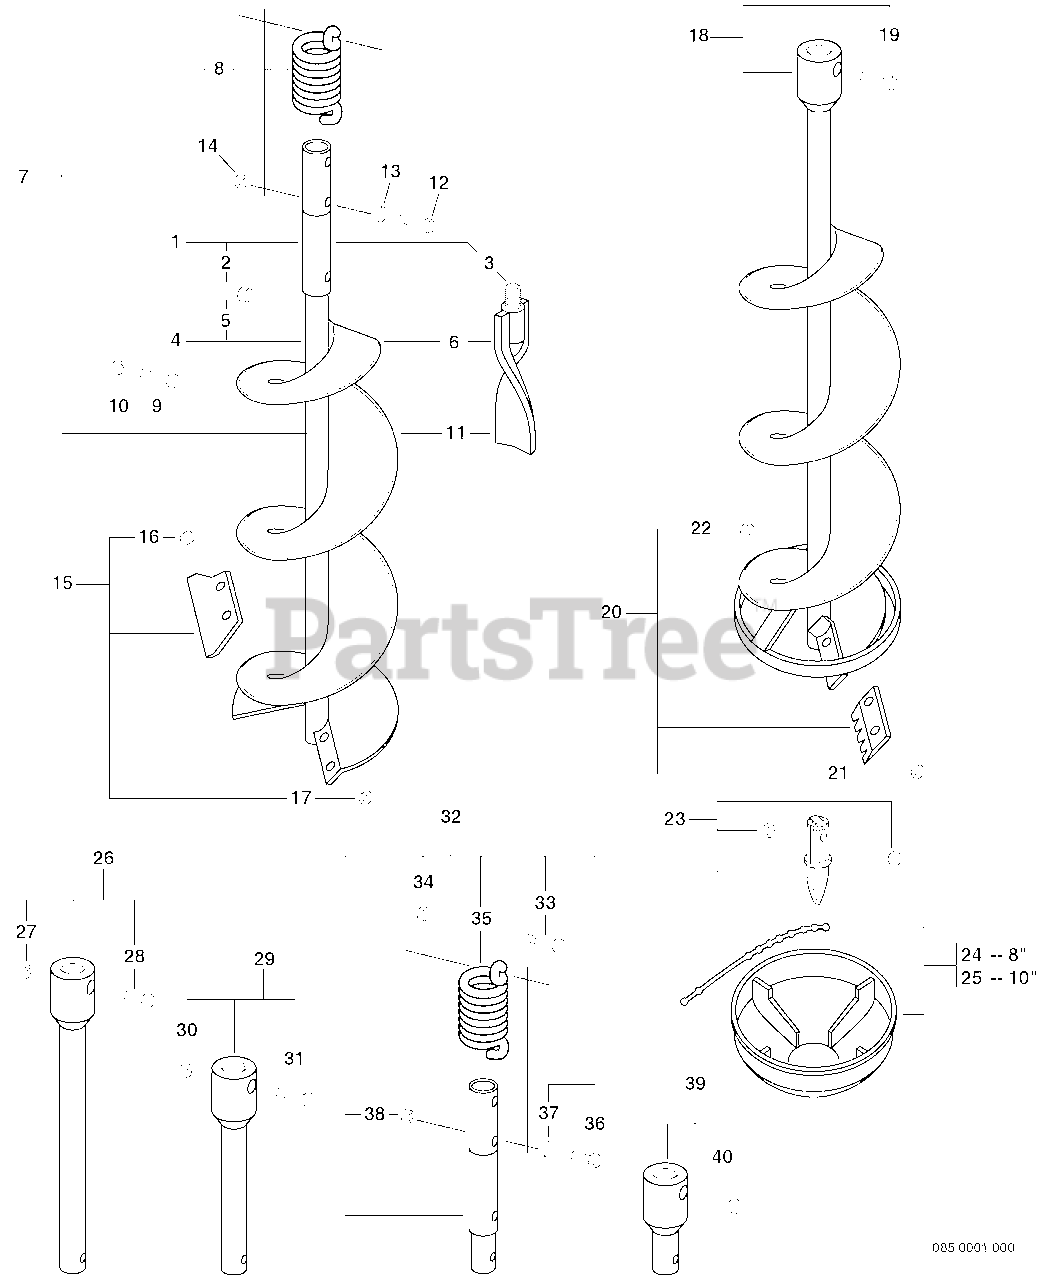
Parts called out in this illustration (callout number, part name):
1	EARTH AUGER W/POINT - 2" DIA.
1	EARTH AUGER W/POINT - 3" DIA.
2	BOLT 3/8"-16×1-1/4"
3	EARTH AUGER POINT - 1" DIA.
4	EARTH AUGER W/POINT - 4" DIA.
5	BOLT 3/8"-16×1-1/4"
6	EARTH AUGER POINT - 2" DIA.
7	EARTH AUGER W/POINT & SPRING - 6" DIA.
7	EARTH AUGER W/POINT & SPRING - 8" DIA.
7	EARTH AUGER W/POINT & SPRING - 10" DIA.
8	SPRING, TENSION
11	EARTH AUGER POINT - 2" DIA.
15	EARTH AUGER BLADE KIT - 4" DIA.
15	EARTH AUGER BLADE KIT - 6" DIA.
15	EARTH AUGER BLADE KIT - 8" DIA.
15	EARTH AUGER BLADE KIT - 10" DIA.
18	DUAL BLADE ICE AUGER - 8" DIA.
18	DUAL BLADE ICE AUGER - 10" DIA.
19	BOLT 3/8"-16×1-1/4"
20	ICE AUGER DUAL BLADE KIT - 8" DIA.
20	ICE AUGER DUAL BLADE KIT - 10" DIA.
23	ICE AUGER POINT KIT
24	ICE AUGER COVER - 8"
25	ICE AUGER COVER - 10"
26	EXTENSION SHAFT - 18" (7/8" DIA)
29	EXTENSION SHAFT - 12" (7/8" DIA)
32	ADAPTER W/SPRING - 7/8" TO 1" DIA.
35	SPRING, TENSION
39	ADAPTER - 7/8" TO 1" DIA.
40	BOLT 3/8"-16×1-1/4"
